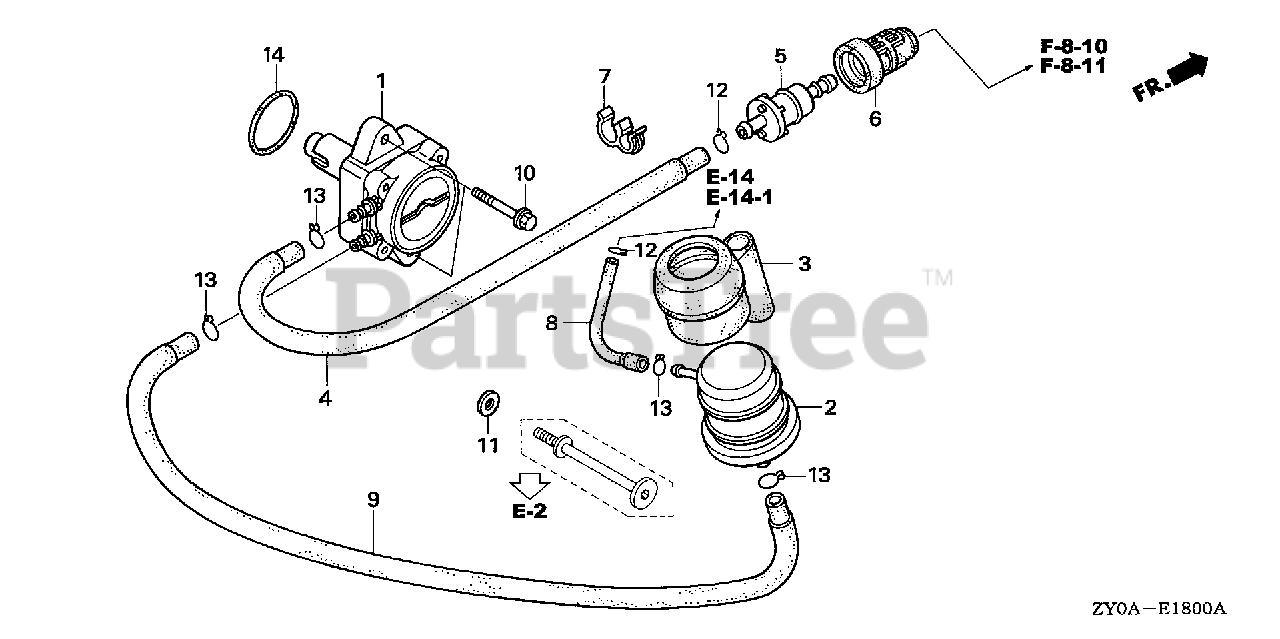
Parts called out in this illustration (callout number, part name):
1	PUMP ASSY., FUEL (MSDS)
2	CHAMBER KIT, FUEL
3	SUSPENSION, FUEL CHAMBER
4	TUBE B, FUEL
5	FILTER, FUEL
6	SUSPENSION, STRAINER
7	CLAMP, TUBE (7.5-11.5) (BLACK)
8	TUBE D, FUEL
9	TUBE C, FUEL
10	BOLT, FLANGE (6X22)
11	WASHER, PLAIN (6X13X1.5)
12	CLIP, TUBE (B10)
13	CLIP, TUBE (B12)
14	O-RING (31.2X2.4)
